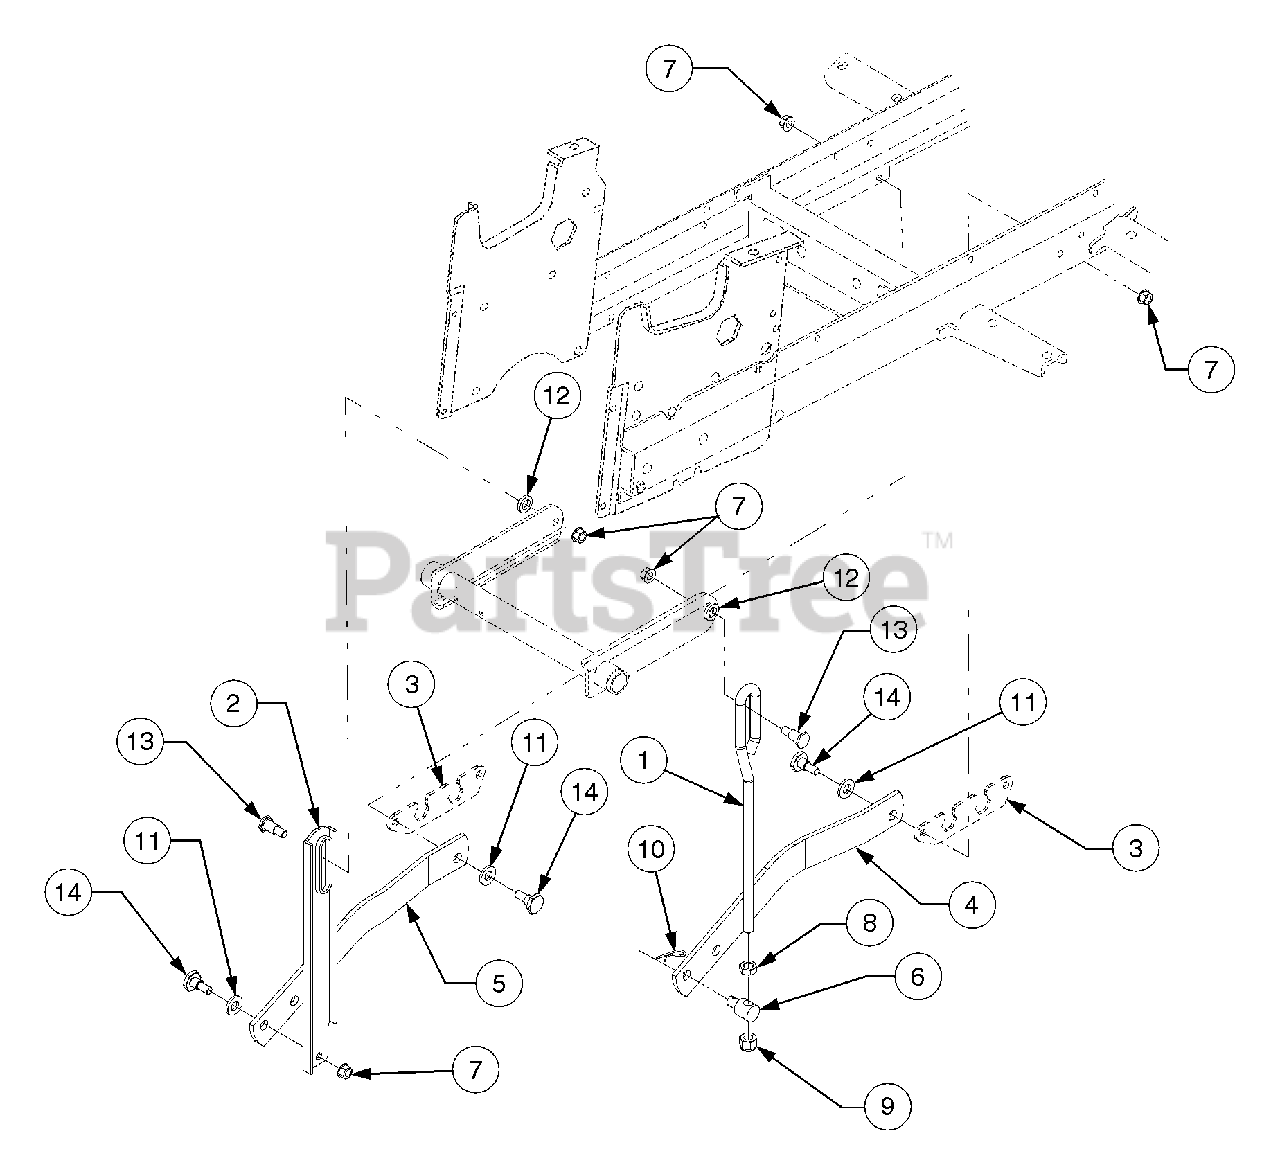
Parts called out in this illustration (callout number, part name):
1	Rod, Lift Link
8	Nut, Hex Flange Lock, 3/8-16
9	Nut, Hex Jam, 1/2-13 GR5
10	Nut, Hex Insert Lock, 1/2-13
11	Pin, Internal Cotter
12	Washer, Flat, .5 x 1.5 x .15
13	Washer, Flat, .531 x .875 x .15
14	Bolt, Shoulder
15	Bolt, Shoulder
